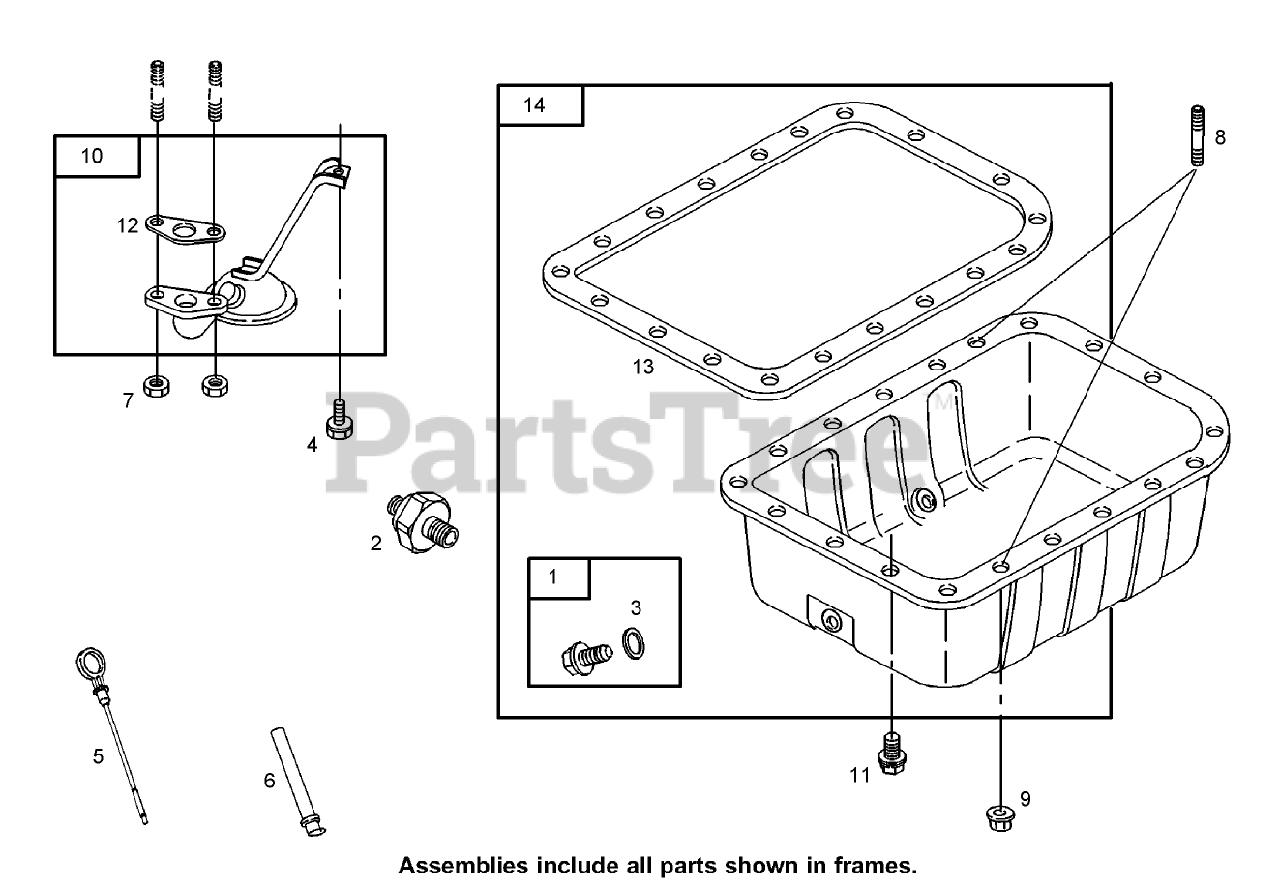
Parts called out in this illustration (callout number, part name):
1	PLUG-DRAIN, OIL
2	SWITCH-PRESSURE, OIL
3	WASHER-SEAL
4	SCREW-HEX
5	OBS DIPSTICK
6	TUBE-DIPSTICK
7	NUT-HEX, METRIC
8	STUD-METRIC
9	NUT-HEX, METRIC
10	SCREEN-PUMP, OIL
11	SCREW-HEX
12	GASKET-STRAINER, OIL
13	GASKET-PAN, OIL
14	PAN-OIL
